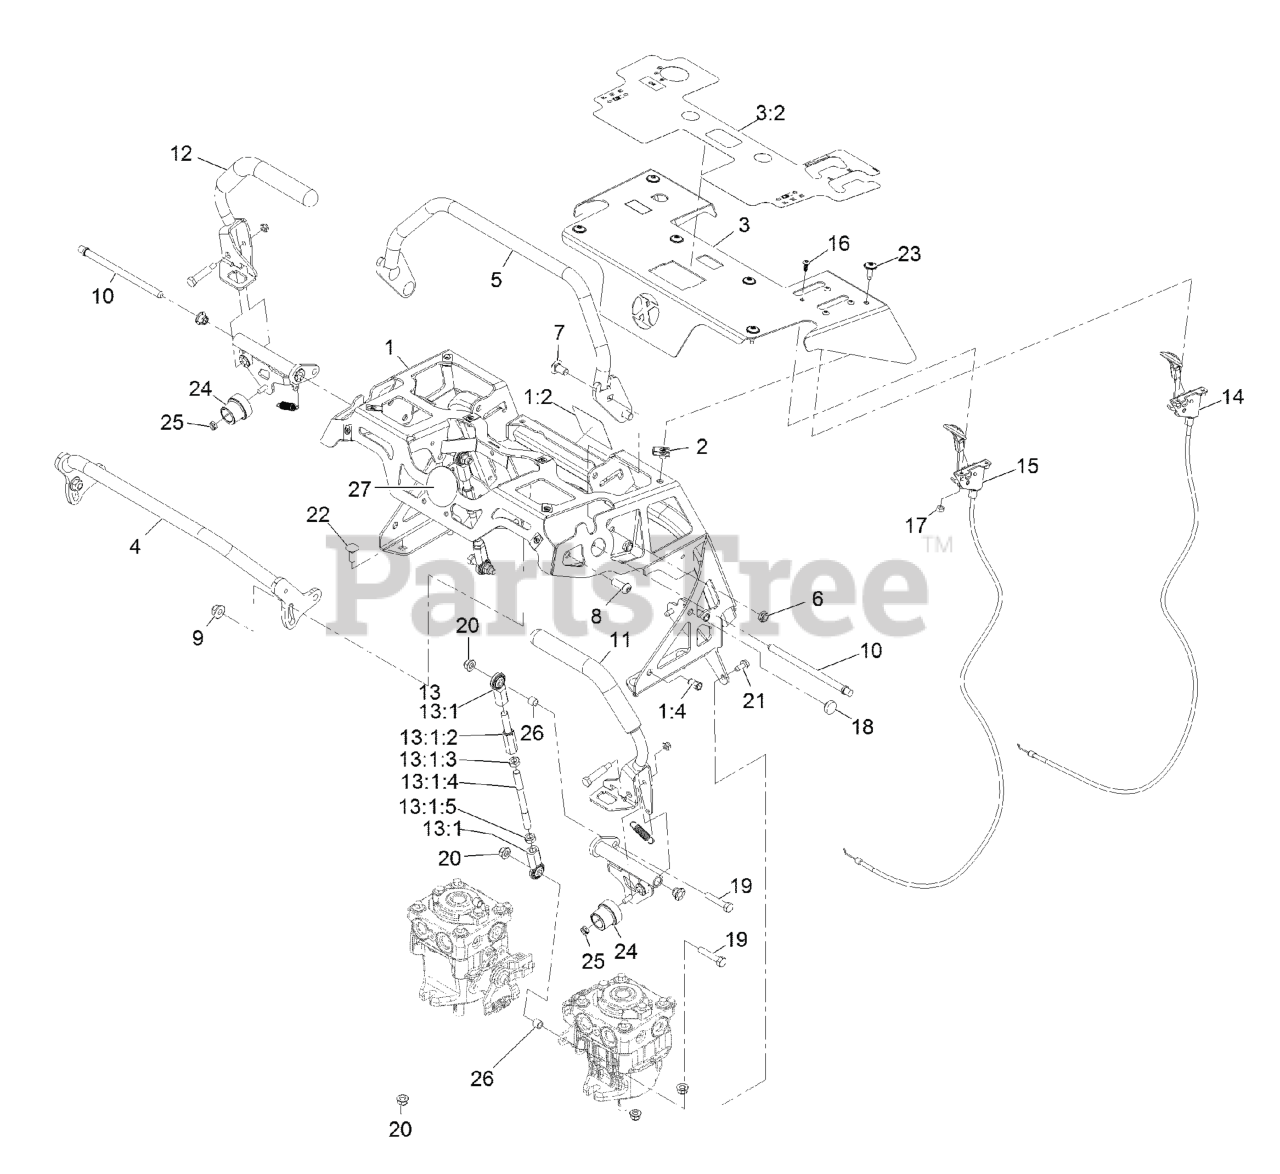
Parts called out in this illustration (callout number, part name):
1	ASM-CTRL TOWER
1:2	DECAL-WARNING
1:4	NUT-CLINCH,HEX
3	ASM, CONTROL PANEL W/ DECALS
3:2	DECAL-CONTROL PANEL NON-EFI
4	WELD, FRONT REF BAR
5	WELD, REAR REF BAR
7	SCREW-CARR
8	SCREW-HSBH
9	NUT-HF, NI
10	PIN, PIVOT
11	ASM, MOTION CONTROL, LT
12	ASM, MOTION CONTROL, RT
13	ASM, LINKAGE
13:1	ASM, Motion Control Link
13:1:2	ROD-ADJUSTMENT
13:1:3	NUT-HEX JAM, LH
13:1:5	NUT-HJ
14	CONTROL, CHOKE
15	CONTROL, THROTTLE
16	SCREW, BHCS
17	NUT-LOCK, NI
19	SCREW-HH
20	NUT-HF, NI
21	SCREW-HWH
22	SCREW-CARR
23	SCREW-TORX
25	NUT-LOCK, NI
27	DECAL-COVER
